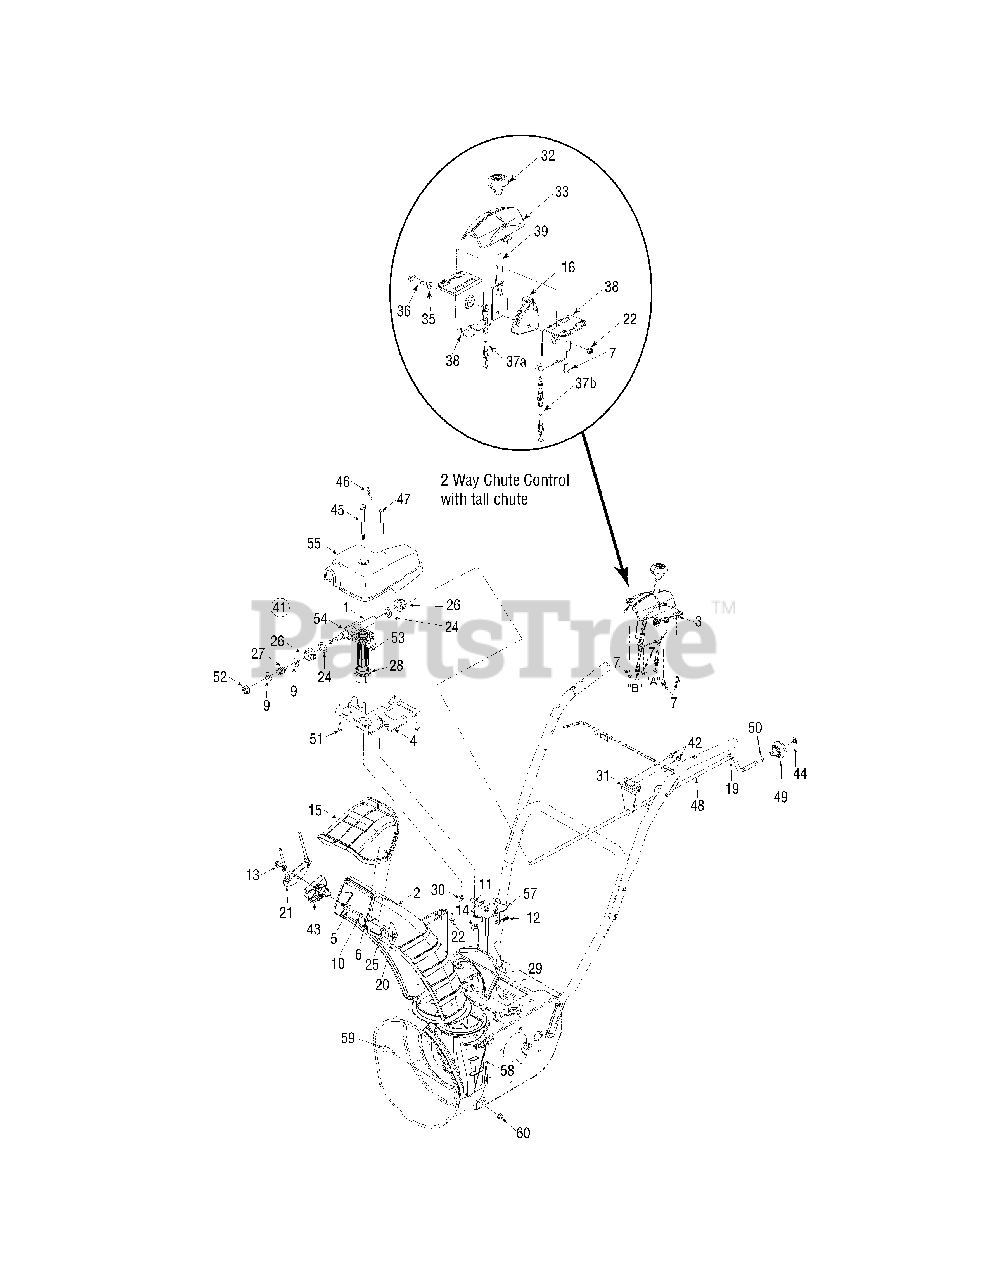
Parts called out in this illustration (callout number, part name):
1	Hex Shaft
2	Tall Lower Chute
3	2 Way Chute control Assembly
4	Chute Gear Ro ta tion Bracket
5	Carriage Bolt 5/16-18 x 1.50 Gr. 2
6	Carriage Screw 5/16-18 x 1.0
7	Hi-Lo Screw 1/4-15 x .5
9	Flat Washer .38 x .92 x .110
10	Hex Tapp Scr 1/4 x .75" Lg.
11	Clevis Pin 3/8 x 1.87
12	Bow Tie Cotter Pin
13	Flange Locknut 5/16-18 Gr. F Nylon
14	Wing Nut 1/4-20
15	Upper Chute w/Ex port Label, Remote
20	Handle Knob Assembly
22	Hex L-Flanged Nut 1/4-20 Gr. F Nylon
24	Flat Washer .625 x 1.0 x .067
25	Flat Washer .349 ID x .879 OD x .063
26	Hex Flg. Bearing
27	Compression Spring .39 x .60 x .88
28	Hex Bearing
29	Hex Hd. Cap Screw 5/16-24 x .75
30	Flat Washer .25 ID x .63 OD x .0515 HT.
31	Support Rod Bracket
33	Control Cover - 2 Way
35	Spring Washer .390 x .625 x .012
36	Flg Shlder Screw .310 x .995: 1/4-20
38	Mounting Bracket - 2 Way
41	Gear box Assembly
42	Hex Wash Hd TT Screw 1/4-20 x .625
44	Push Nut 3/8" Rod
45	Flg. Shoulder Screw .312 x 3.5: 1/4-20
46	Internal Cotter Pin
47	Hex. Hd. Cap Screw 1/4-20 x 3.0 Gr. 5
48	Chute Crank .375 Dia. x 30.5" Lg.
50	Flat Washer .375 x .738 x .063
51	Hi-Lo Screw #12-16 x .75
52	Hex L-Flanged Nut 3/8-16 Gr. F Nylon
53	Gear 14 teeth he li cal w/hub
54	Worm - Nylon
55	Cover
57	Chute Support Bracket Ass'y
58	Chute Adapter
59	Carriage Screw 1/4-20 x .75 Gr. 5
60	Hex L-Flanged Nut 1/4-20 Gr. F Nylon
